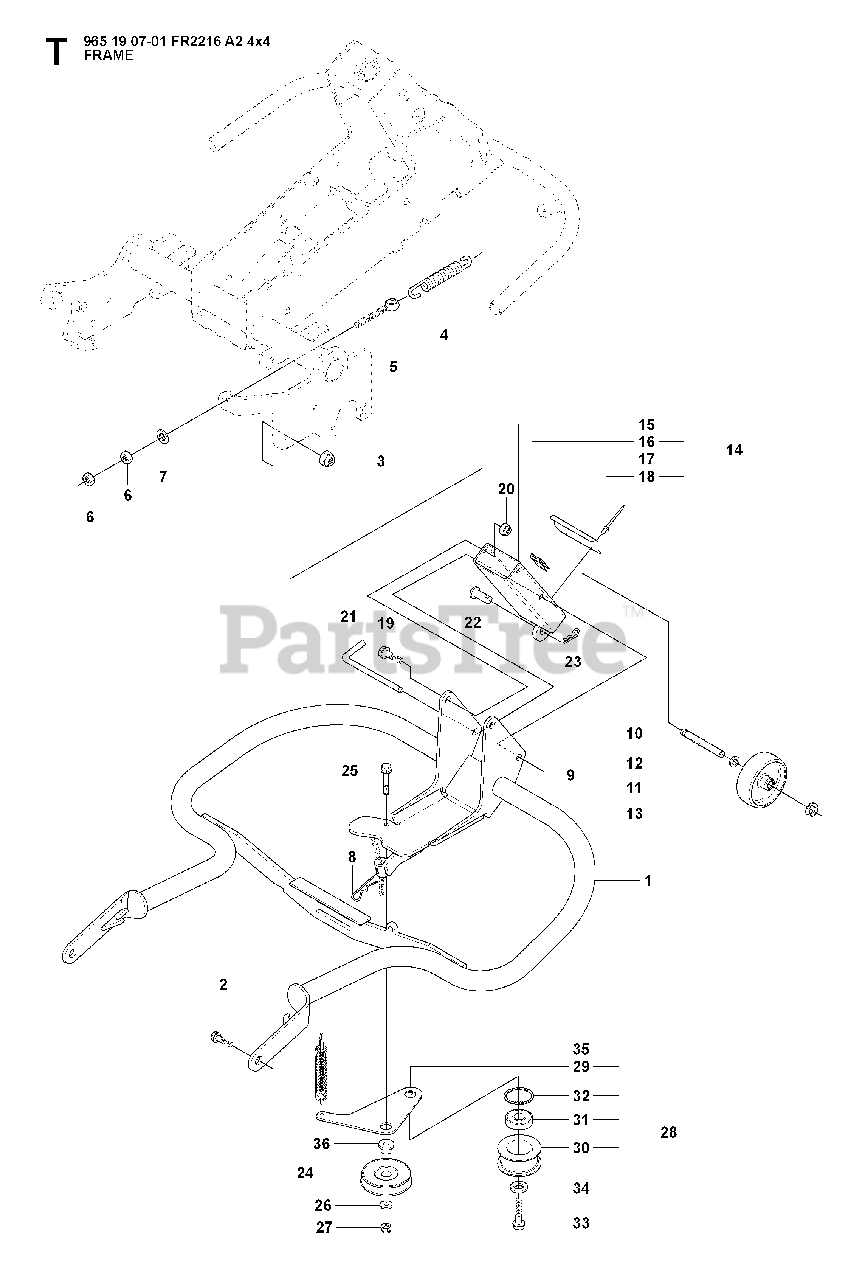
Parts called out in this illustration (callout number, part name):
7	WASHER
9	WHEEL ASSY
13	RETAINING RING
14	LINK ASSY
20	LOCKNUT M8
27	LOCKNUT M8
28	BELT TENSIONER ASSY
29	TENSIONER
30	%PULLEY
31	BALL BEARING 6004-2RS1
32	RETAINING RING
